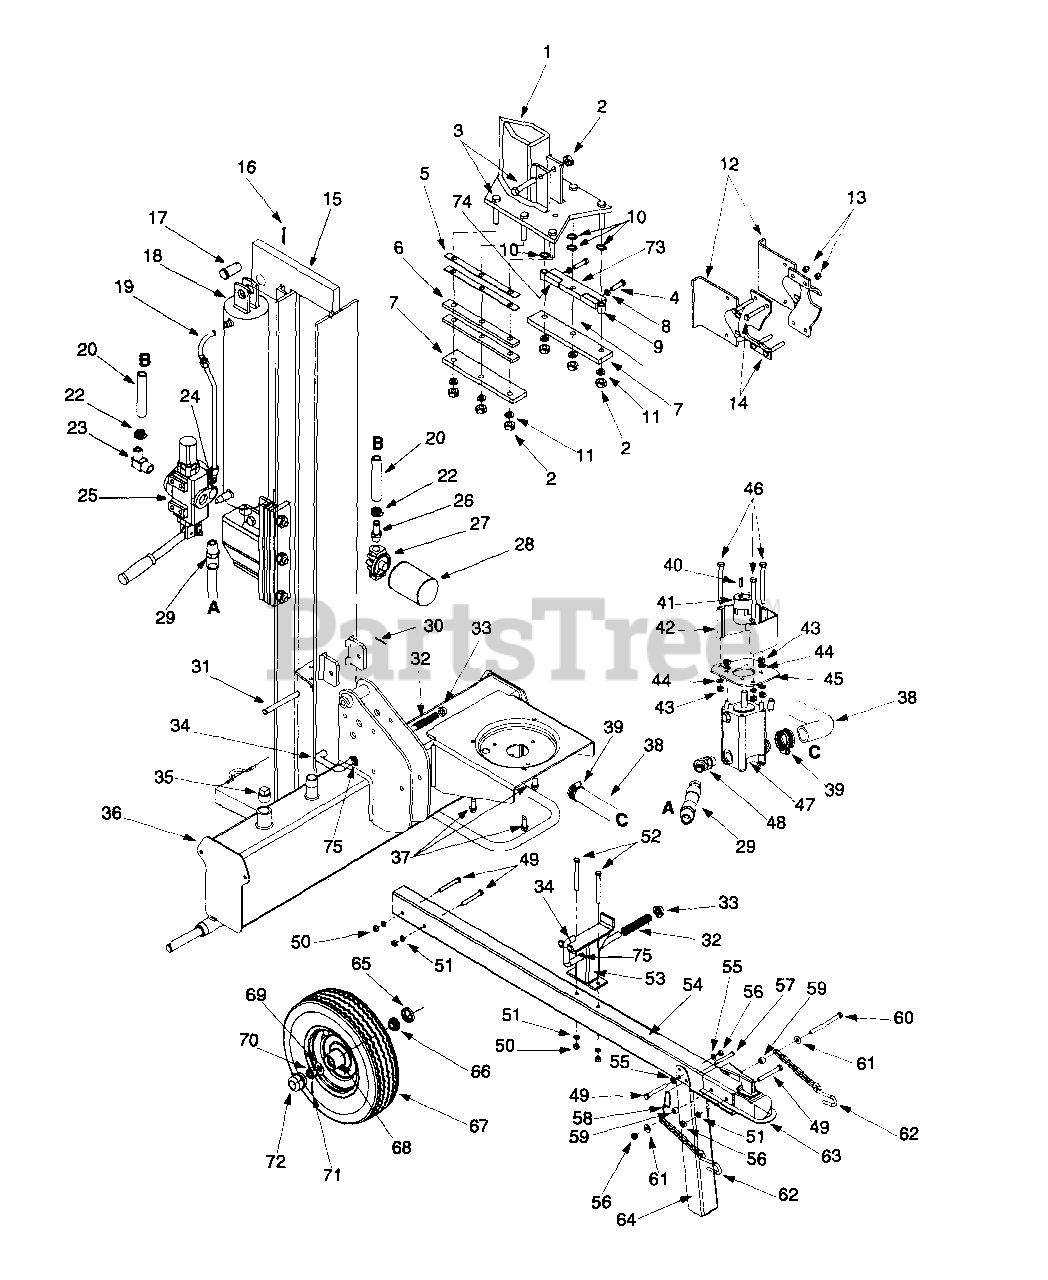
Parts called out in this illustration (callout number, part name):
2	Lock Nut 1/2-20
3	Hex Cap Screw 1/2-20 x 2.75
4	Hex Cap Screw 3/8-24 x 1.5
8	Hex Jam Nut 3/8-24
9	Spacer
10	Flat Washer .531 x .93 x .090
11	Lock Washer 1/2
14	Hex Cap Screw 3/8-16 x 2.5
17	Clevis Pin
20	Return Hose 3/4" I.D. x 44" Lg.
22	Hose Clamp 5/8"
23	Return Elbow
24	90° Solid Male Adapter
26	3/4" Hose Adapter
27	Filter Housing
28	Oil Filter
29	High Pressure Hydraulic Hose
30	Cotter Pin 1/8" Dia.
31	Hinge Pin 1/2 x 4.8" Lg.
32	Comp. Spring 4' Lg.
33	Push Cap
34	Locking Rod
35	Pipe Plug
38	Suction Hose
39	Hose Clamp
40	Sq.-Key 3/1 6" x .75"
41	Flexible Coupling
42	Coupling Shield
43	Hex Nut 5/16-24
44	L-Wash. 5/16" I.D.
46	Hex Screw 5/16-24 x 3.25
47	Gear Pump (11 GPM)
48	45 Degree Elbow
49	Hex Bolt 3/8-16 x 3" Lg.
50	Hex Nut 3/8-16 Thd.
51	L-Wash. 3/8" I.D.
52	Hex Bolt 3/8-16 x 4" Lg.
55	Flat Washer 3/8
56	Hex L-Nut 3/8-16 Thd.
57	Clevis Pin 5/16 x 2.5" Lg.
58	Spring Pin
59	Spacer 3/8" I.D. x .625" O.D.
60	Hex Bolt 3/8-16 x 4" Lg. (Grd 5)
61	Fl-Wash.3/8" I.D.x.87" O.D.
62	Chain - Tow Hitch
63	Hitch Coupler
66	Bearing Cone
67	Wheel Asm Comp. - Gray
68	Bearing Cup
69	Fl-Wash..76" I.D. x 1.5" O.D.
70	Slotted Nut 3/4-16 Thd.
71	Cotter Pin 5/32" Dia. x 1-1/4" Lg.
72	Hub Cap
75	Flat Washer .635 ID x .93 OD
